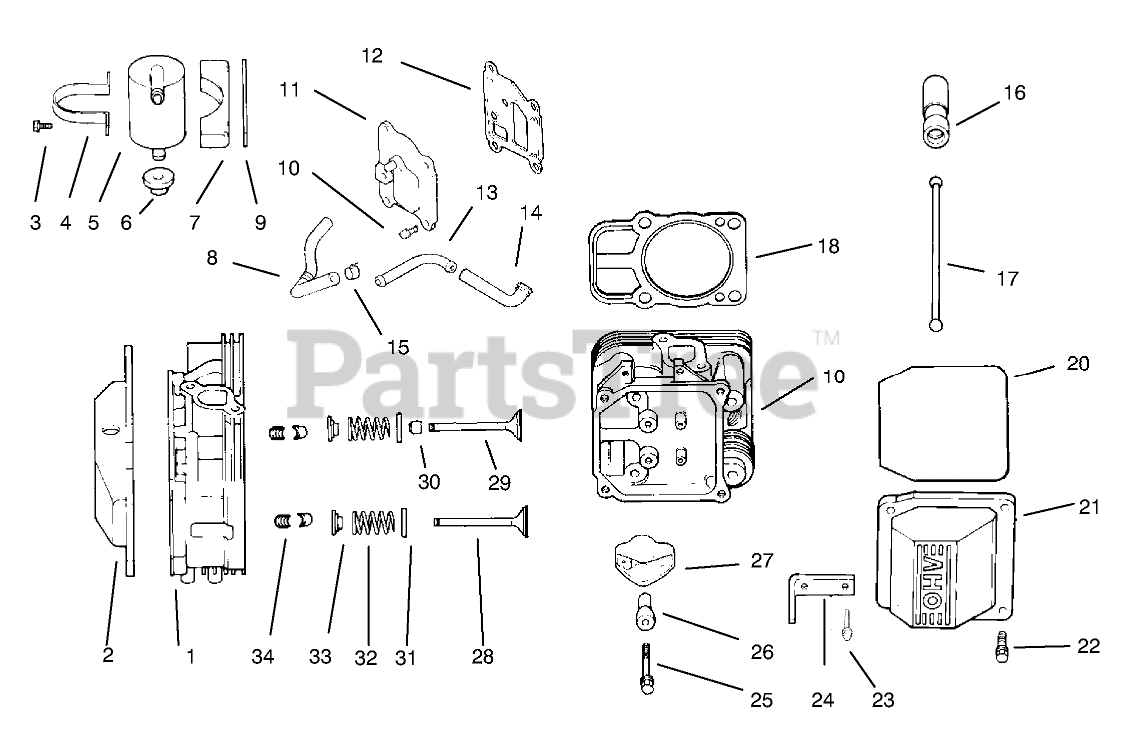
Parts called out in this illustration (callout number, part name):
1	#1 Cyl. Head Asm
2	Cover-Rocker
3	Kit-Breather INC 4
4	Grommet-Rubber
5	Cover-Breather
6	Screw
7	Hose-Breather
8	Retainer Kit
9	Cap-Spring, Valve
10	Spring-Valve
11	Retainer-Spring
12	Valve-Exhaust
13	Valve-Intake
14	Seal-Stem, Valve
15	Fitting
16	Hose-Breather
17	Lifter-Valve
18	Rod-Push
19	Gasket-Cylinder Head
20	#2 Cyl. Head Asm,
21	Arm-Rocker
22	Pivot-Rocker Arm
24	Cover-Rocker
25	Screw
26	Screw
27	Strap-Lifting
